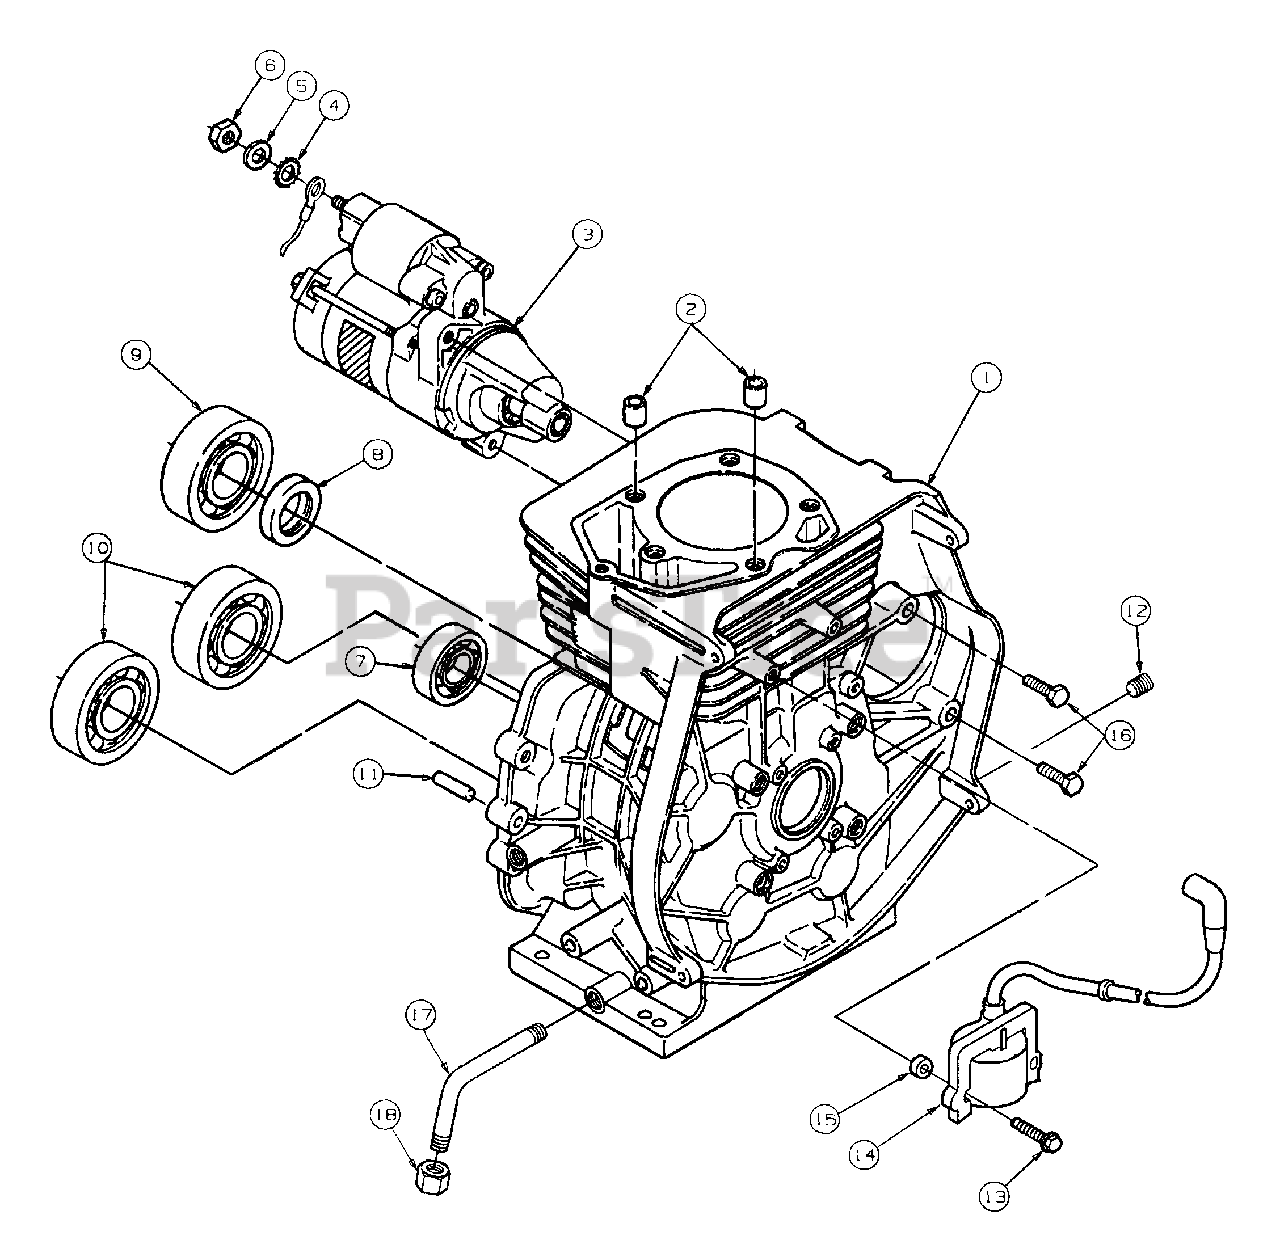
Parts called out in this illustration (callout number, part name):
1	Engine, Complete
2	Pin, Hollow Dowel
4	Washer, ET Lock, 5/16
5	Washer, Flat, 5/16
6	Nut, Hex, M8 x 1.25
7	Bearing, Camshaft
8	Seal, Crankshaft Oil
9	Bearing, Crankshaft
10	Bearing Balancer Shaft
11	Pin, Alignment
12	Plug, 1/4 NPT Countersunk Hd
13	Screw, Pan Head, M6 x 1 x 30
14	Coil, Ignition
15	Spacer, Ignition Coil, M6 x 30
16	Screw, Hex Hd, M8 x 1.25 x 40
17	Pipe, Oil Drain
18	Cap, Oil Drain
